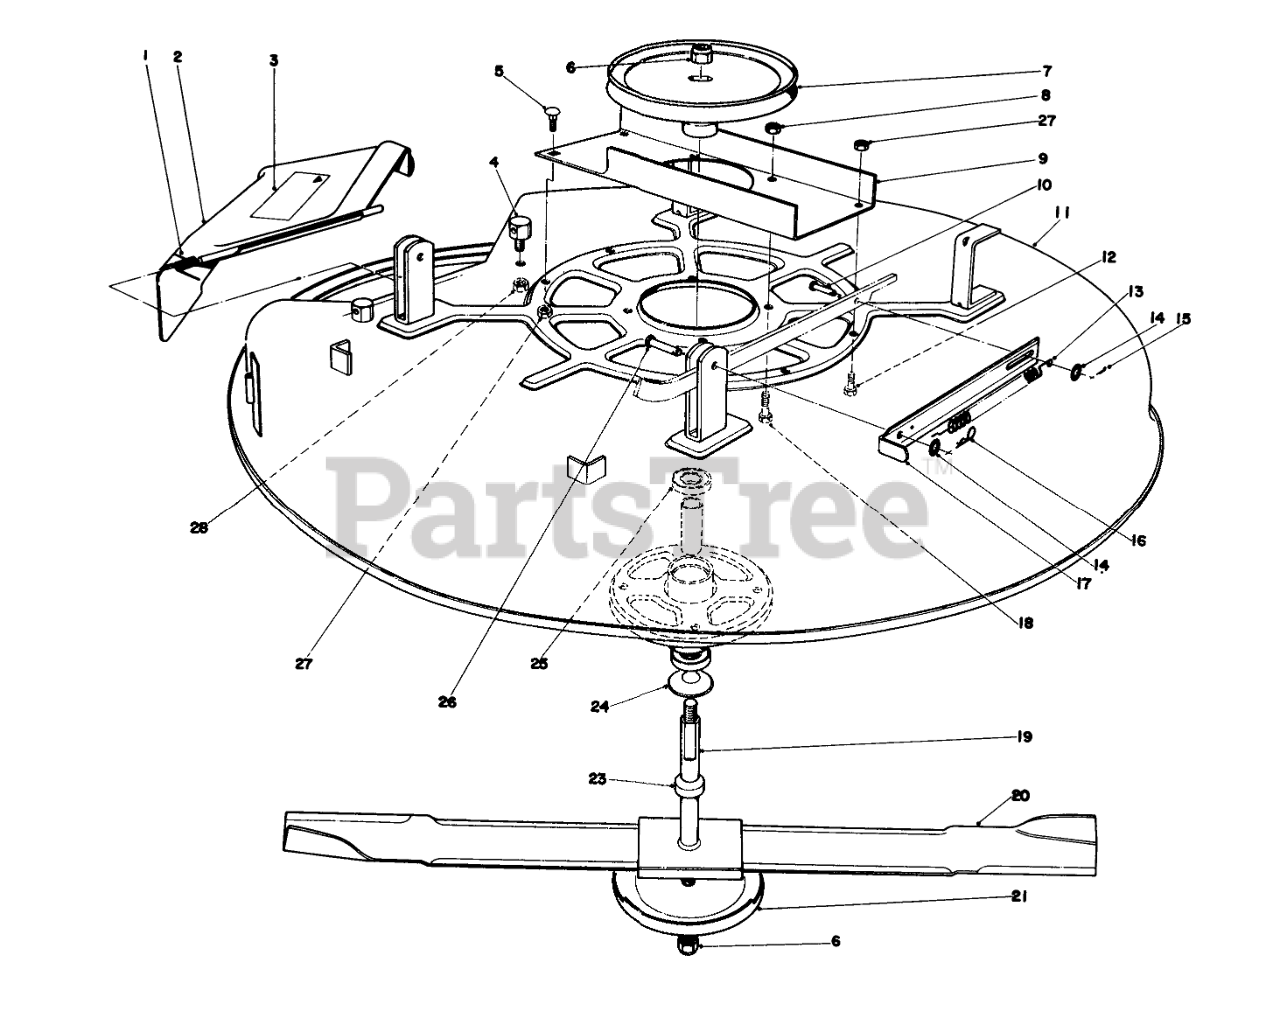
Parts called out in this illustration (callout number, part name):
1	SPRING
2	Deflector Assembly (Incl. Ref. #3)
3	Decal
4	POST-PIVOT
5	SCREW-CARR
7	BLADE DRIVE PULLEY
8	NUT-LOCK, CONE
9	REINFORCEMENT CHANNEL
10	PIN-CLEVIS
11	Cutter Deck
12	SCREW-HH
13	DECK TENSION SPRNG O
14	WASHER-FLAT
15	PIN-COTTER
16	PIN-COTTER
17	DECK SPRING STRAP R
18	SCREW-HH
19	Spindle Assembly (Incl. Ref. #23-25)
20	Blade
21	Cup
23	SPACER
24	DUST COVER
25	BEARING
26	PIN-CLEVIS
27	NUT-HEX, SIDE DEFORM
28	NUT-LOCK, SIDE
